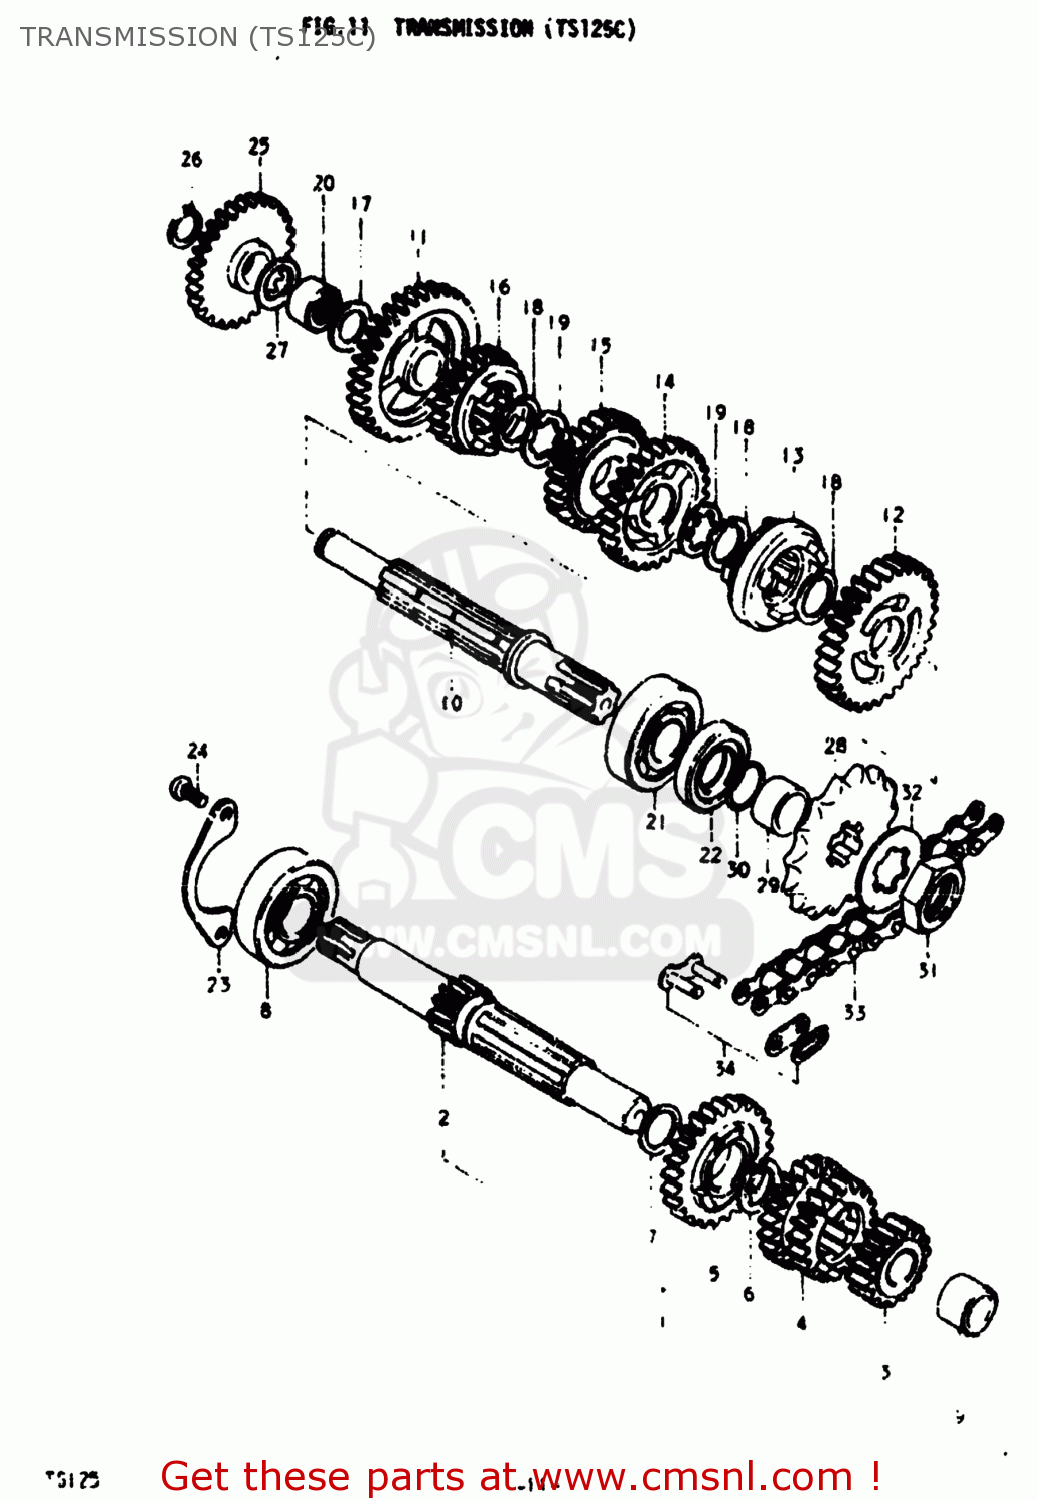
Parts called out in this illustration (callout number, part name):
1	SHAFT ASSEMBLY,COUNTER
2	SHAFT,COUNTER
3	GEAR,SECOND DRIVE
4	GEAR,THIRD/FOURTH DRIVE
5	GEAR,FIFTH DRIVE
6	CIRCLIP
7	WASHER
8	Bearing
9	BUSH(15X22X15)
10	SHAFT,GEAR SHIFT
11	GEAR,1ST DRIVEN
12	GEAR,SECOND DRIVEN
13	WHEEL,SECOND DRIVEN GEAR
14	GEAR,THIRD DRIVEN
15	GEAR,FOURTH DRIVEN
16	GEAR,FIFTH DRIVEN
17	WASHER,THRUST
18	CIRCLIP
19	WASHER,LOCK
20	BEARING(15X22X12)
21	Bearing
22	SEAL,OIL(25X40X7)
23	RETAINER,CNTR SHAFT BEARING
24	SCREW 6X12
25	GEAR,KICK STARTER IDLE
26	CIRCLIP,15MM
27	WASHER,THRUST
28	SPROCKET,ENGINE
29	SPACER(20X25X12.5)
30	O RING(D:1,ID:19.5)
31	NUT
32	WASHER,LOCK
33	CHAIN ASSEMBLY,DRIVE
34	JOINT ASSEMBLY,CHAIN
